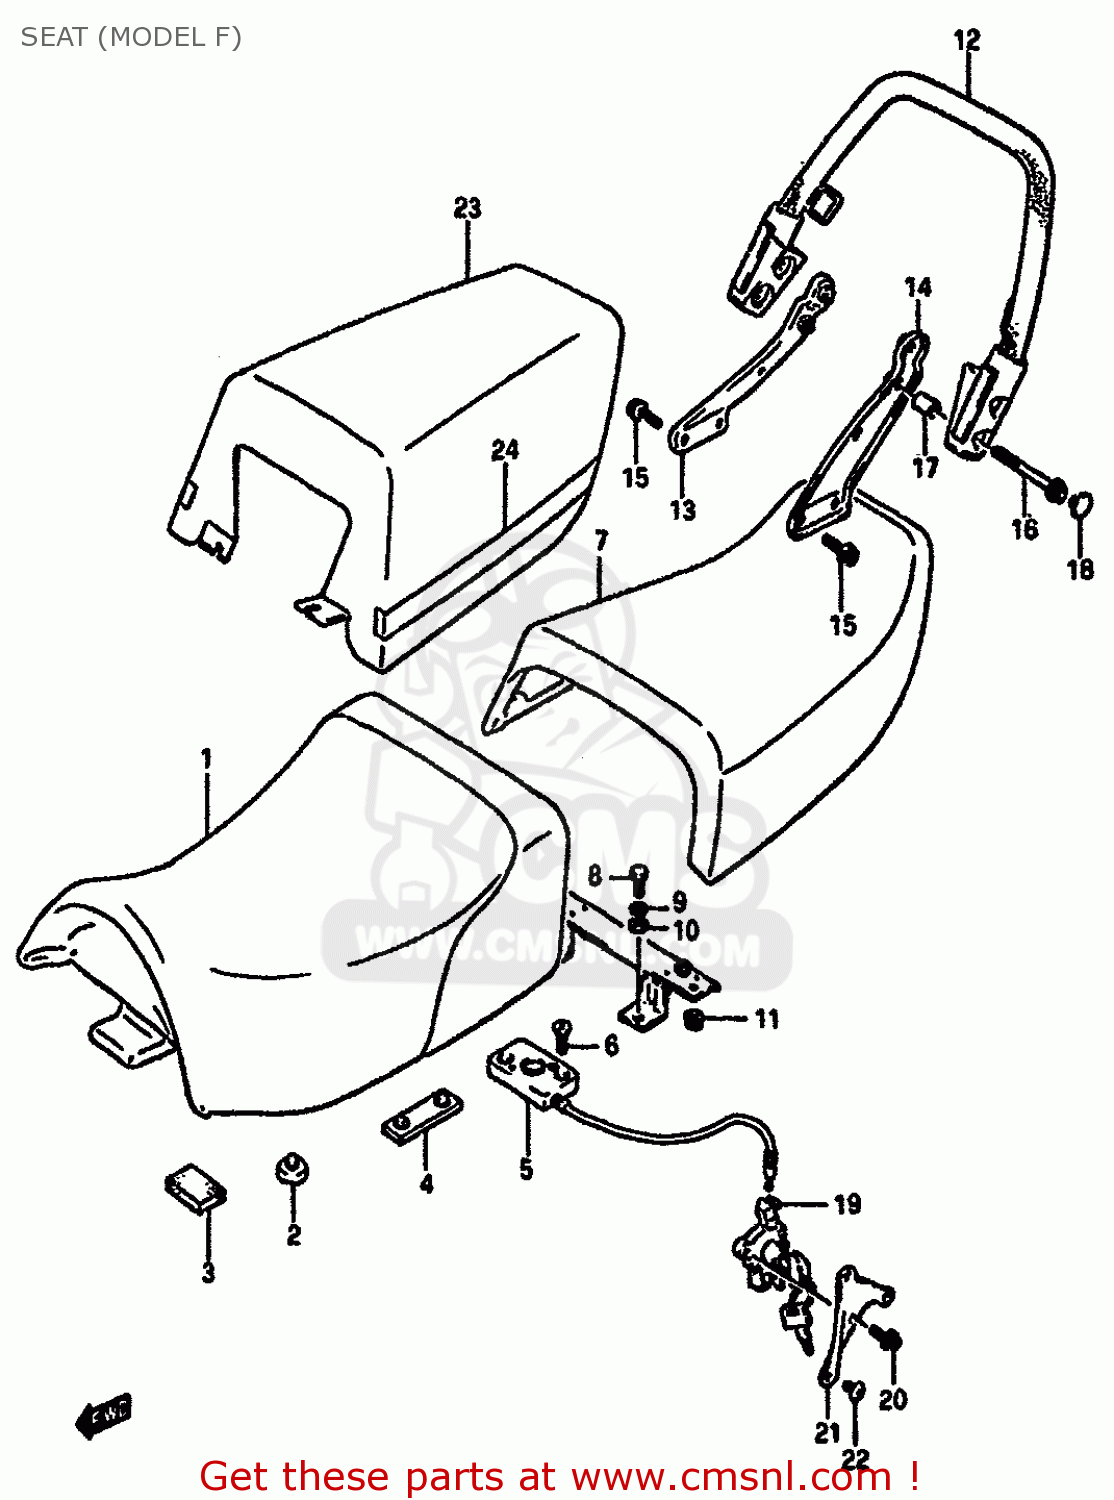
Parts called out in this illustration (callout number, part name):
1	SEAT ASSY (RED)
2	CUSHION(11.5X22X20)
3	CUSHION,TOOL(40X30X15)
4	CUSHION
5	BRACKET,SEAT SUPPORT,R
6	SCREW
7	SEAT ASSY,PILLION (RED)
8	BOLT
9	WASHER,LOCK
10	WASHER(6.5X16X1.2)
11	NUT
12	HANDLE,PILLION RIDER
13	PLATE,PILLION HANDLE,R
14	PLATE COMP,PILLION HANDLE
15	BOLT
16	BOLT
17	SPACER (8.6X13.8X21.5)
18	CAP(OD:10)
19	LOCK SET
20	PLUG ,6X20
21	BRACKET,SEAT LOCK
22	SCREW 6X12
23	BOX SET
24	TAPE SET,SEAT TAIL BOX
